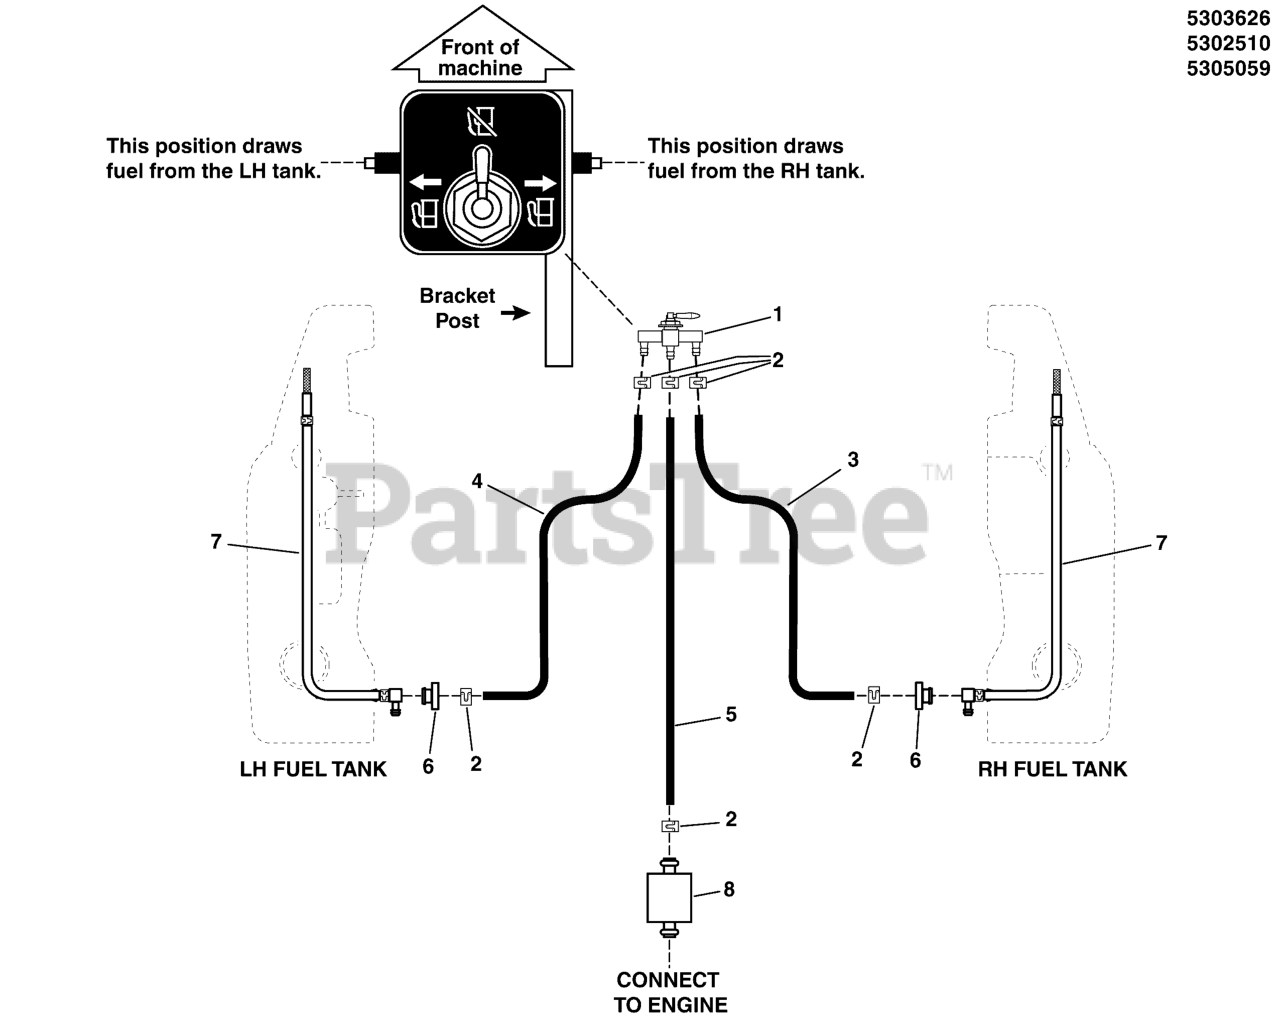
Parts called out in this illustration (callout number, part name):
1	VALVE, FUEL SHUT-OFF, 11772
2	CLAMP, HOSE, EXTERNAL, 1/2 - RED
3	HOSE, 1/4" FUEL, 27.00"
4	HOSE, 1/4" FUEL, 42.00"
5	HOSE, 1/4" FUEL, 13.00"
6	BUSHING-FUEL TANK RED RUBBER
7	PICK UP TUBE ASSEMBLY, FUEL LINE (SV)
8	FUEL FILTER (SV)
